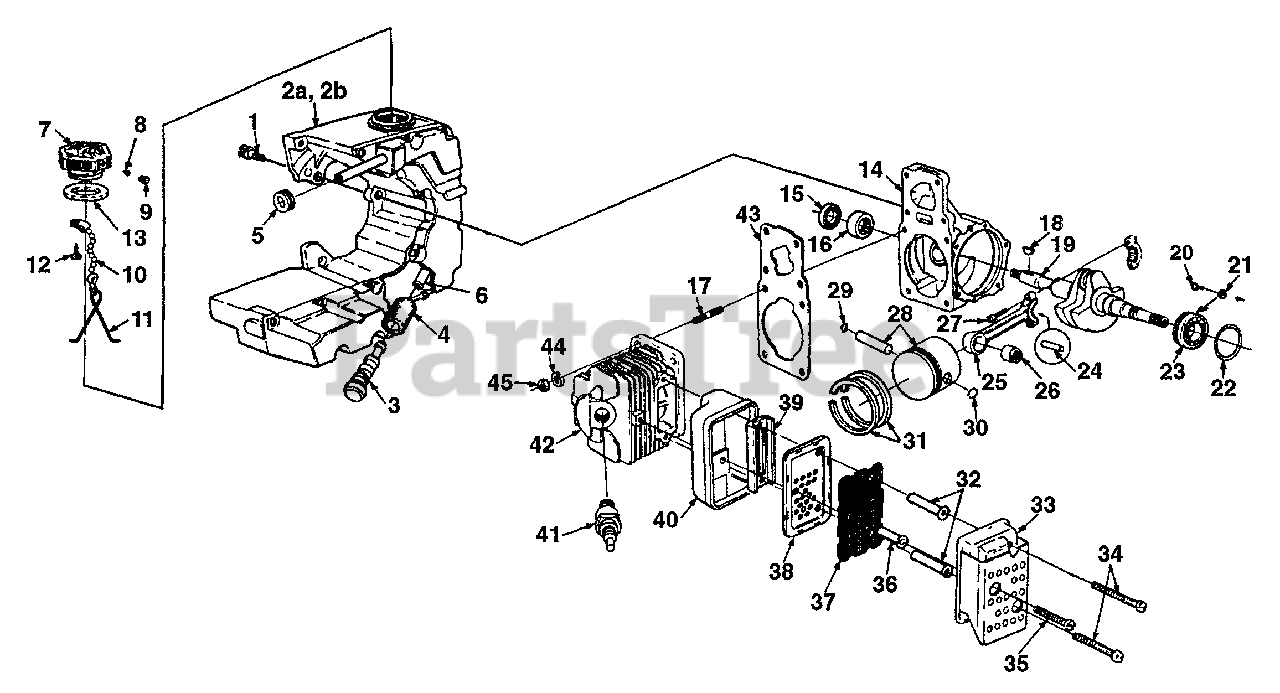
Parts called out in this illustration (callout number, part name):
1	SCREW-Shoulder
2A	FUEL TANK
2B	FUEL TANK
3	FILTER-Fuel
4	FELT FILTER
5	GROMMET
6	TUBING-Rubber (9 1/4")
7	CAP-Fuel Filler
8	VALVE Check
9	FILTER-Fuel Cap
10	CHAIN-Bead
11	RETAINER
12	SCREW-Pan Hd. (#6 X 1/4")
13	GASKET-Fuel Filler Cap
14	CRANKCASE
15	SEAL
16	BEARING
17	STUD-Cylinder
18	KEY-Woodruff
19	CRANKSHAFT
20	SCREW-Torx
21	WASHER-Lock
22	RING-Retaining
23	BEARING-Ball
24	ROLLER SET (31)
25	ROD-Connecting
26	BEARING
27	SCREW-Cap Soc. Hd.
28	PISTON & PIN
29	RING-Retaining
30	RING-Retaining
31	PISTON RING
32	SPACER-Muffler
33	CAP-Muffler & Shield
34	SCREW-Hex Hd. (12-24 X 2 1/4")
35	SCREW-Hex Hd. (12-24 X 1 7/8")
36	SPACER-Muffler
37	SCREEN-Spark Arrestor
38	BAFFLE-Muffler
39	PLATE-Muffler
40	BODY-Muffler
41	SPARK PLUG (CJ8)
42	CYLINDER
43	GASKET - Cylinder
44	WASHER-Lock (1/4")
45	NUT (1/4 - 28)
